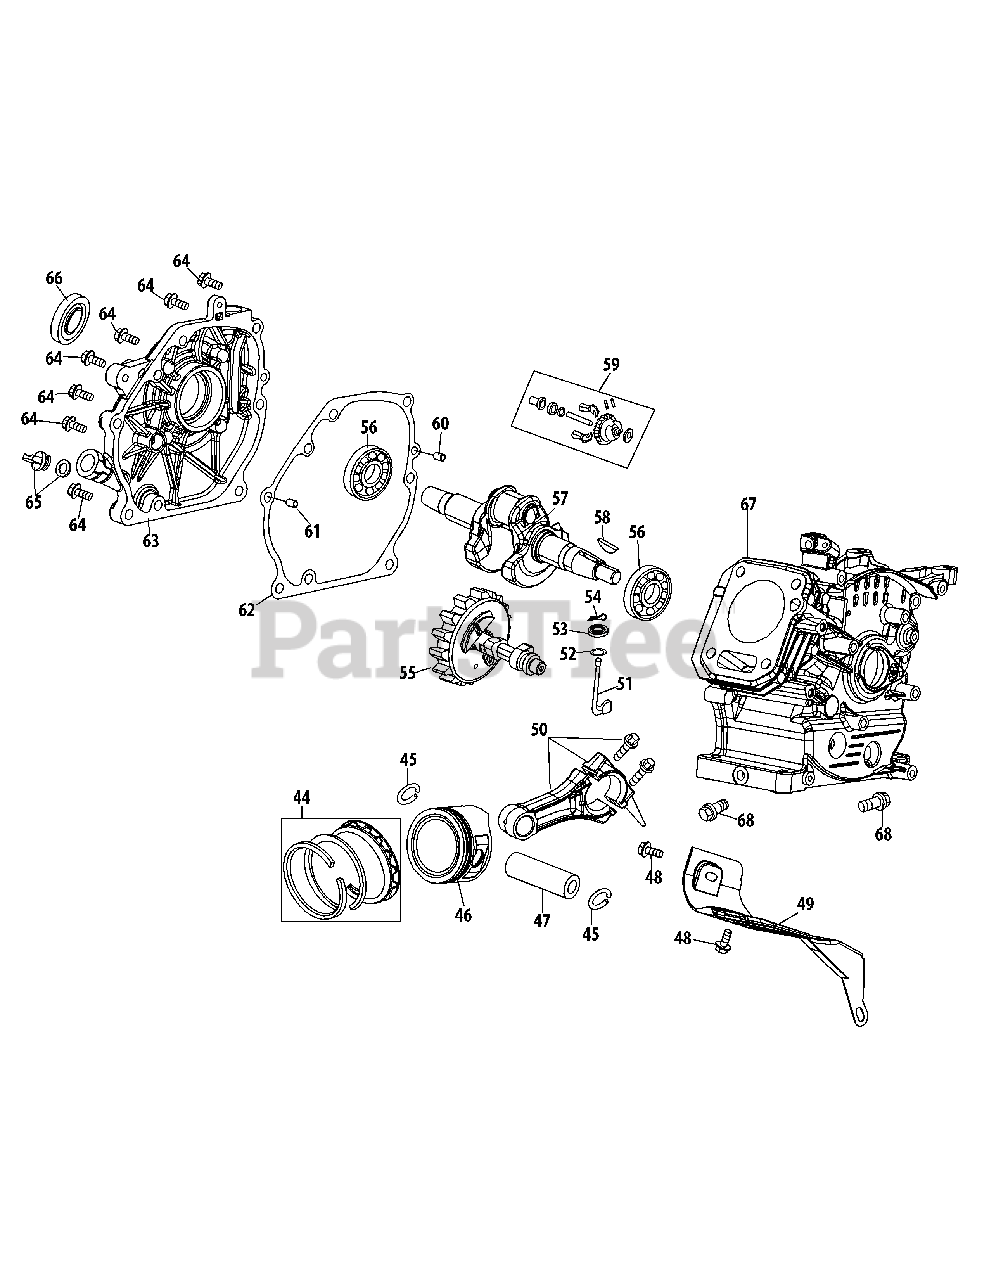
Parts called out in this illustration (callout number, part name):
44	Piston Ring Set
45	Piston Pin Snap Ring
47	Piston Pin
48	Bolt M6×12
49	Air Shield
50	Connecting Rod Assembly
51	Governor Arm Shaft
52	Washer, 5.2×1.9
53	Governor Seal
54	Cotter Pin
55	Camshaft Assy.
56	Radial Ball Bearing, 6205
57	Crankshaft Assembly
58	Woodruff Key
59	Governor Gear/Shaft Assembly
60	Dowel Pin, 7×14
61	Dowel Pin, 9×14
62	Crankcase Cover Gasket
63	Cover Comp, Left Crankcase
64	Bolt M8×32
65	Dipstick Assembly
66	Oil Seal, 25×41.25×6
67	Short Block
68	Oil Drain Plug
